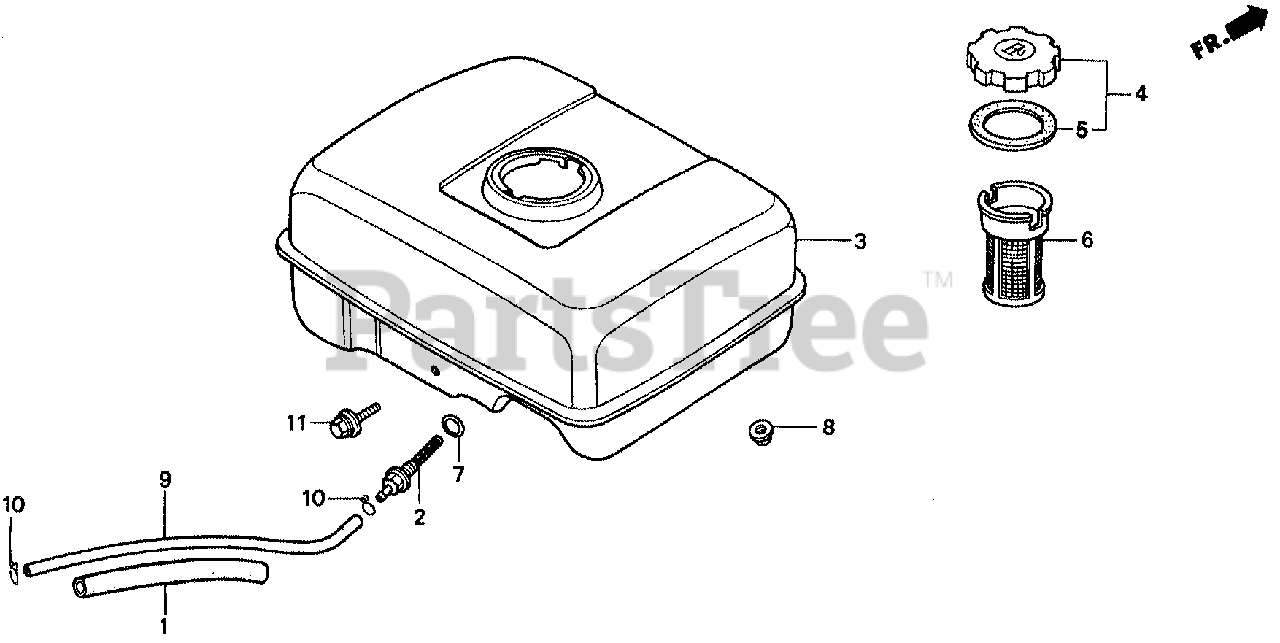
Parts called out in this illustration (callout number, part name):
1	RUBBER, SUPPORTER (107MM)
2	JOINT, FUEL TANK
3	TANK, FUEL *R8* (BRIGHT RED)
3	TANK, FUEL *R280* (POWER RED)
4	CAP, FUEL FILLER
5	GASKET, FUEL FILLER CAP
6	FILTER, FUEL
7	O-RING (13.5X1.5) (ARAI)
8	NUT, FLANGE (6MM)
9	BULK HOSE, FUEL (4.5X3000) (4.5X140)
10	CLIP, TUBE (B8)
11	BOLT, FLANGE (6X29)
11	BOLT, FLANGE (6X25)
